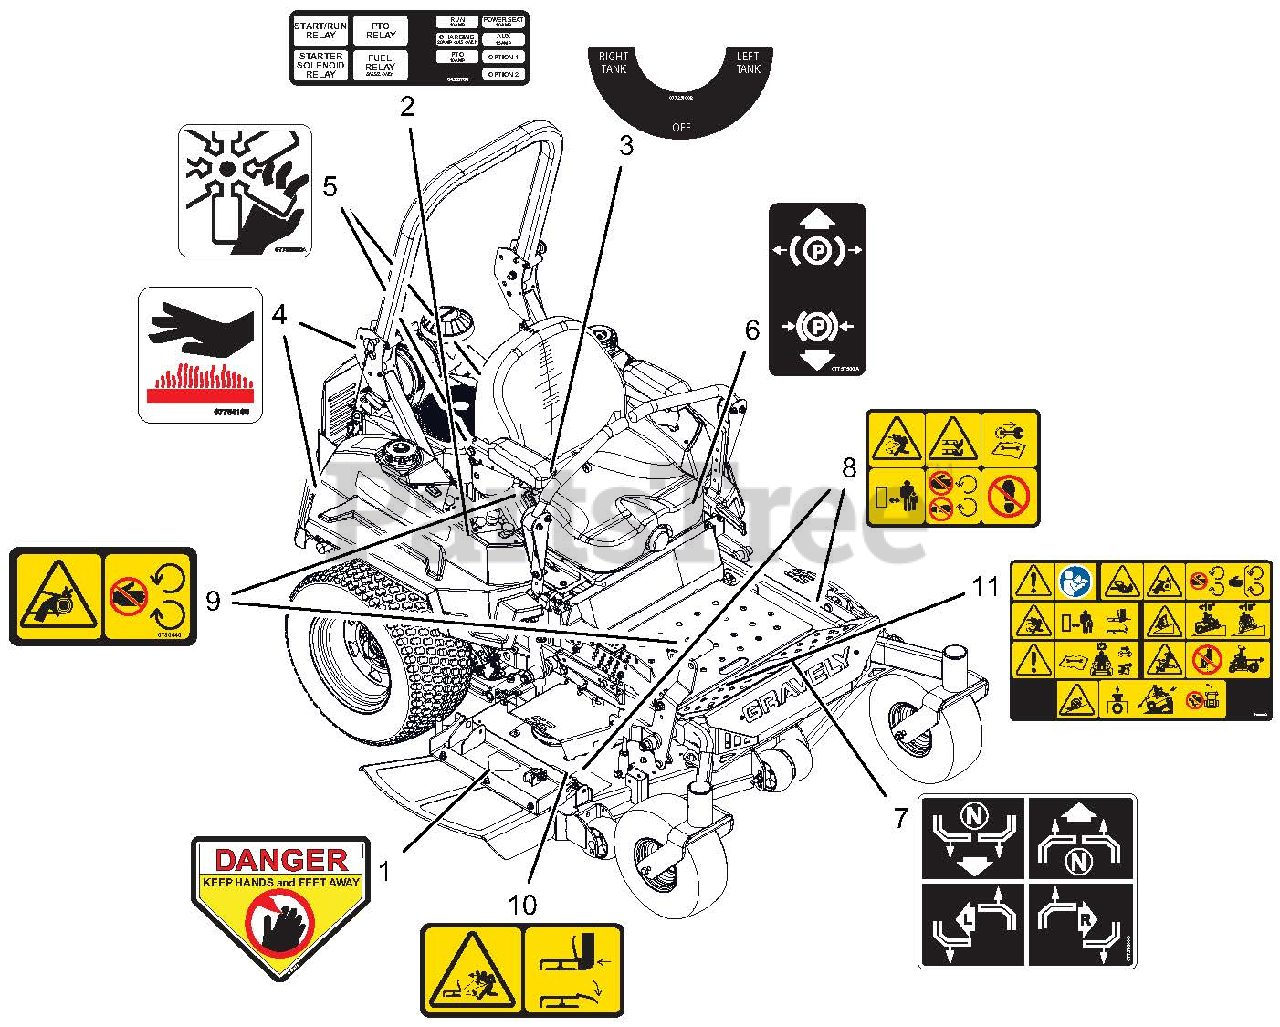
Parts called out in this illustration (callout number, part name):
1	DECAL, DANGER
2	DECAL, FUSE BOX
3	DECAL, FUEL CONTROL VALVE
4	DECAL HOT SURFACE
5	DECAL, DANGER - FAN
6	DECAL, PARKING BRAKE LEVER
7	DECAL, INSTRUCTIONAL - STEERING
8	DECAL, SAFETY - MOWER DECK
9	DECAL, SAFETY - GUARDING
10	DECAL, SAFETY - DECK GUARDING
11	DECAL, MAIN SAFETY, COMMERCIAL
